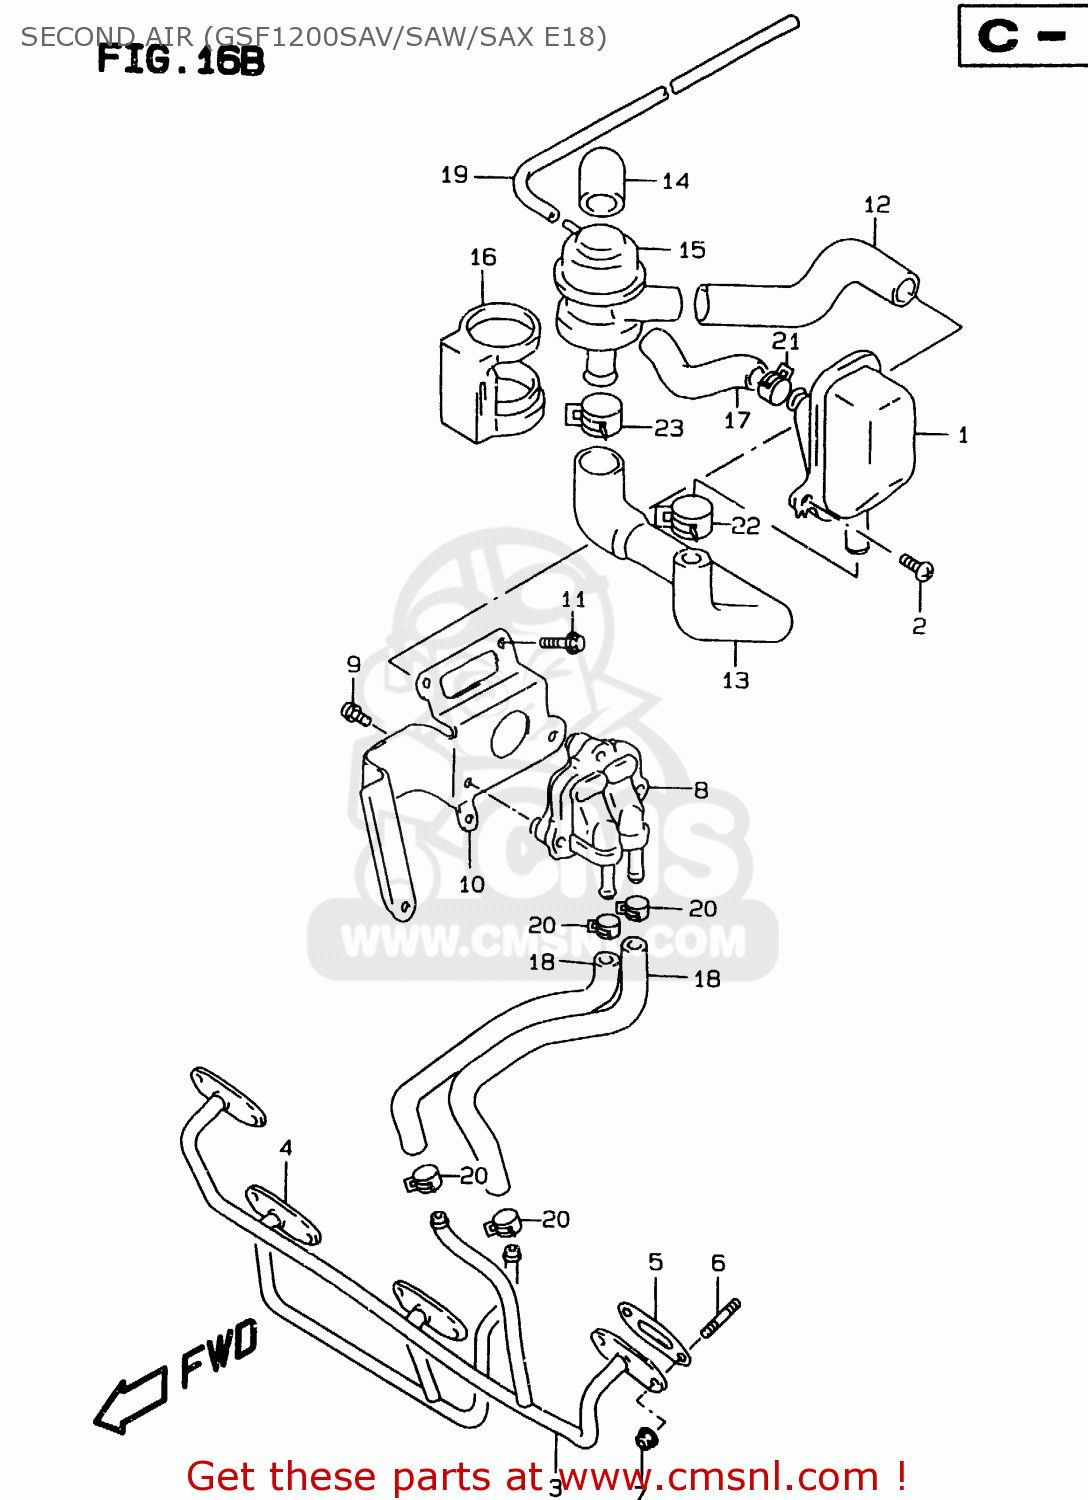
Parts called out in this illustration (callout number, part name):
1	CLEANER ASSY,2ND AIR
2	SCREW
3	PIPE COMP,SECOND AIR,OUTER
4	PIPE COMP,SECOND AIR,INNER
5	GASKET,SECOND AIR PIPE (NAS)
6	STUD BOLT
7	NUT
8	VALVE ASSY,2ND AIR REED
9	BOLT
10	BRACKET COMP,REED VALVE
11	BOLT
12	HOSE,SECOND AIR SWITCH VALVE
13	HOSE,SECOND AIR CLEANER
14	CAP,SWITCHING VALVE
15	VALVE ASSEMBLY,SECOND AIR SWITCH
16	CUSHION,2ND AIR VALVE
17	HOSE,SECOND AIR CLEANER INLET
18	HOSE(9X14X600)
19	HOSE(4X7X600)
20	CLIP
21	CLIP
22	CLIP
23	CLIP
